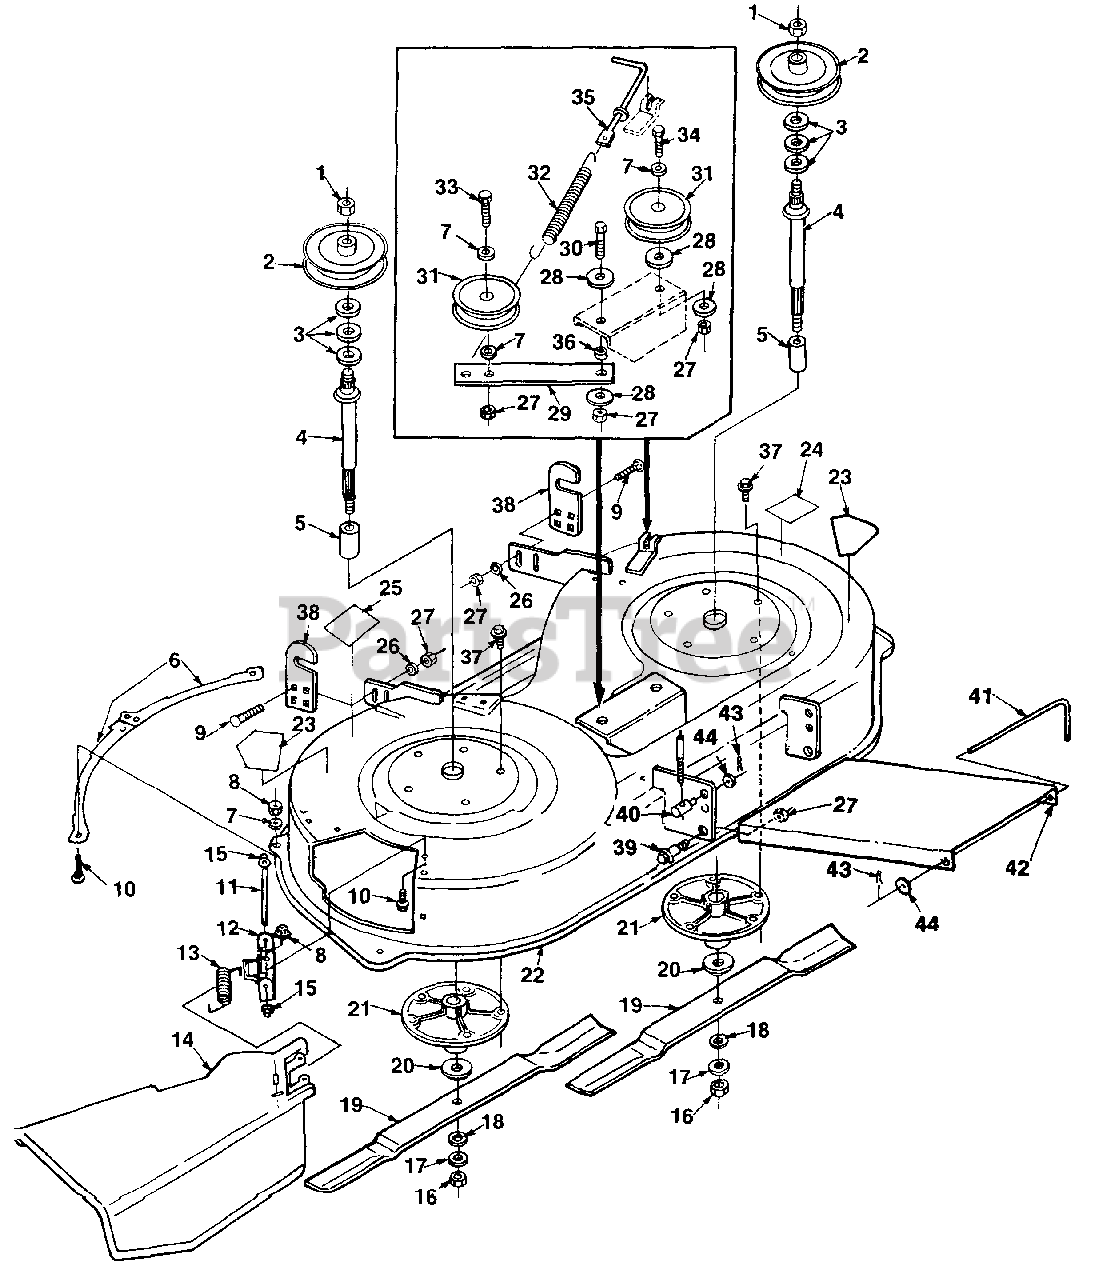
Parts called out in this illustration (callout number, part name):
1	NUT-Center Lock (9/16-18)
2	PULLEY- Cutter head
3	WASHER- Flat
4	SPINDLE- Cutter head
5	SPACER- Spindle
6	PLATE- Air cut off
7	WASHER- Flat (3/8")
8	NUT- Flange (5/16-18)
9	BOLT- Rd. hd., sq. neck (3/8-16 x 1 1/4")
10	BOLT- Rd. hd., sq. neck
11	ROD- Deflector
12	BRACKET- Chute hinge
13	SPRING- Torsion
14	CHUTE- Deflector Assy.
15	NUT- Pal, push (3/8")
16	NUT- Hex (9/16-18)
17	WASHER- Flat
18	WASHER- Belleville
20	BLADE- Adaptor
21	HOUSING- Spindle
22	DECK ASSEMBLY
23	DECAL- Danger
24	DECAL- No step
25	DECAL- Belt installation
26	WASHER- Flat
27	NUT- Hex lock (3/8-16)
28	WASHER- Blade mtg.
29	ARM- Idler
30	SCREW- Hex hd., cap (3/8-16 x 1 1/2")
31	PULLEY- Idler
32	SPRING- Extension
33	SCREW- Hex hd., cap (3/8-16 x 1 3/4")
34	SCREW- Hex hd., cap (3/8-16 x 2")
35	ROD- Spring release
36	SPACER- Idler arm
37	SCREW- Hex washer hd.
38	BRACKET- Rear hanger
39	BOLT- Shoulder
40	PIN- Clevis
41	PIN- Link
42	BRACKET- Link
43	PIN- Hair cotter
44	WASHER- Flat
